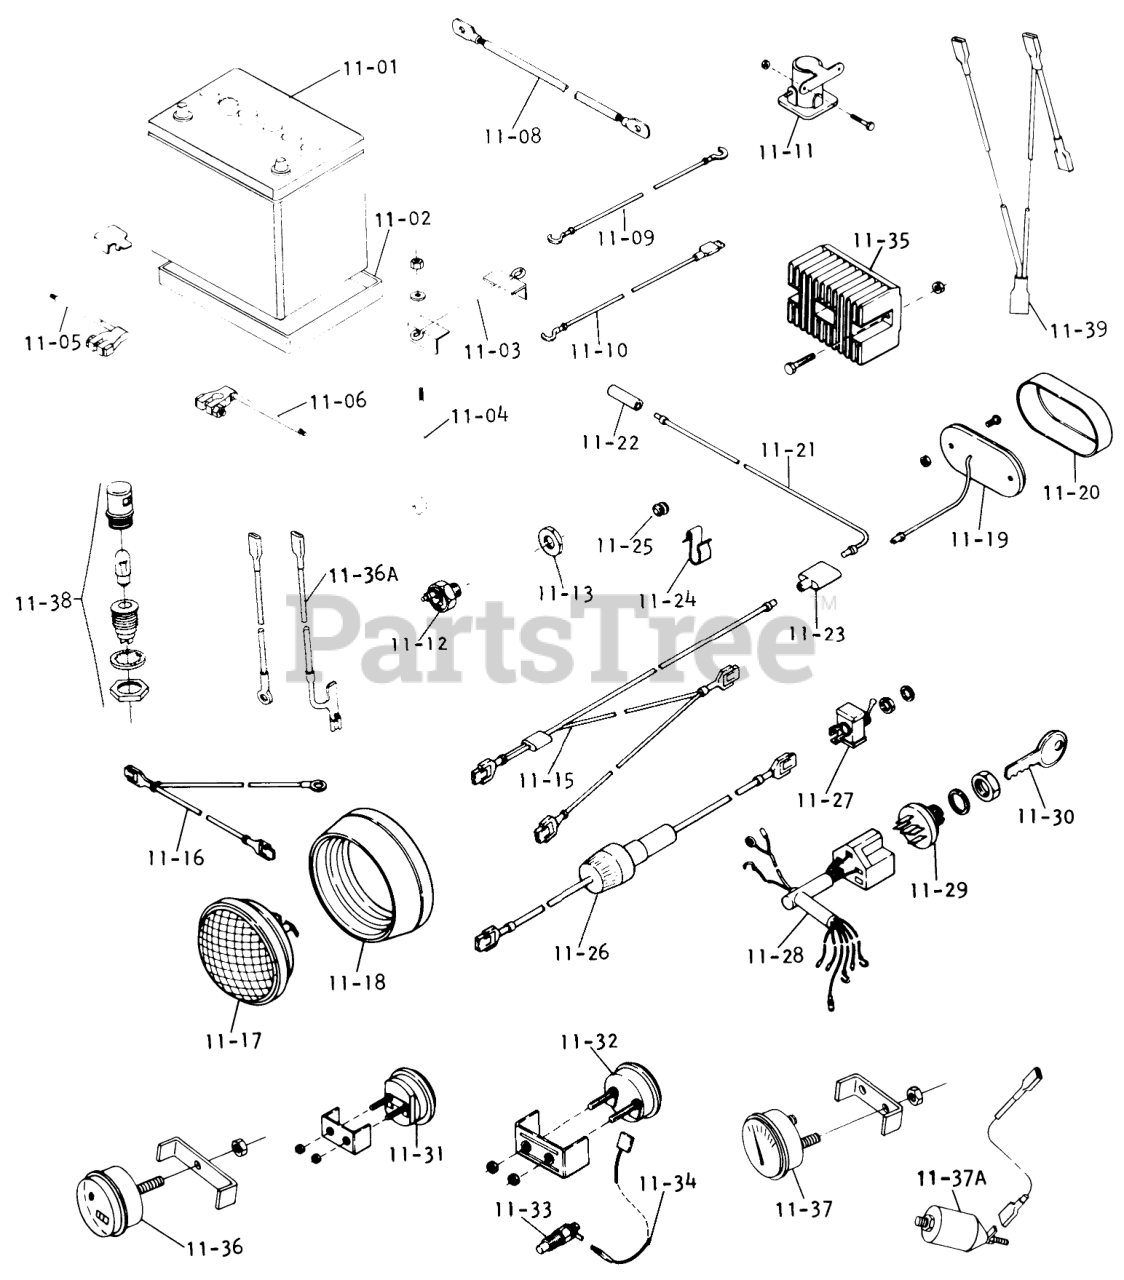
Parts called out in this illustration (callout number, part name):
11-01	Battery
11-02	Battery Box
11-03	Assy-Hold Down
11-04	Hook-Battery Retainer
11-05	ASSY-WIRE SOLENOID
11-06	Wire Assy.-Ground
11-08	Starter-Solenoid 20 1/2"
11-09	WIRE ASSY
11-10	Assy-Wire
11-11	Solenoid
11-12	SWITCH SAFETY
11-13	NUT-SPECIAL 9/16-18
11-15	Control Clip
11-16	Wire Assy
11-17	HEADLAMP
11-18	Grommet
11-19	Base-Taillight
11-20	Lens-Taillight
11-21	Wire assembly
11-22	CONNECTOR 2 WIRE
11-23	CONNECTOR 3 WIRE
11-24	SPEED CLIP
11-25	Grommet
11-26	ASSY FUSED CONNECTOR
11-27	SWITCH-LIGHTS
11-28	Harness-Main Wiring
11-29	SWITCH-IGNITION
11-30	Key-EL
11-31	AMMETER W/CLAMP
11-32	Gauge-Oil Temp
11-33	Assy-Thermistor
11-34	Assy-Wre
11-35	REGULATOR-RECTIFIER
11-36	Hour Meter
11-36A	Wire Assy
11-37	Gauge-Oil Pressure
11-37A	SENDER-OIL PRESSURE
11-38	LAMP-DASH
11-39	Assy-Wire Gauge
